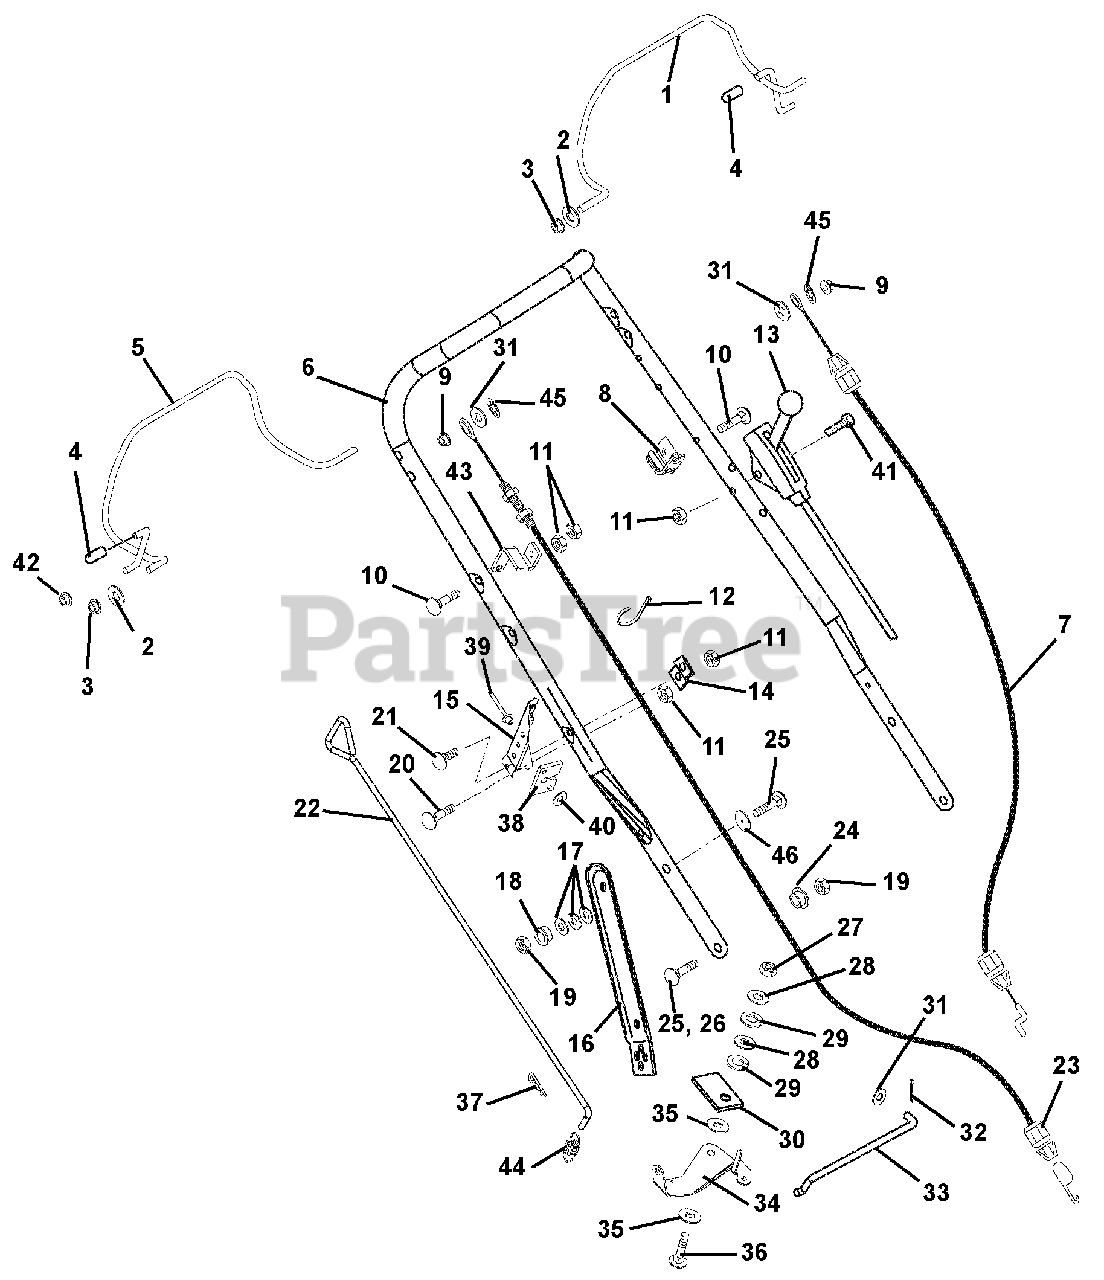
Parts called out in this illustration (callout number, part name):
1	BAIL, WBLM ENGINE
2	@WSHR-FL-STL.344X.688X.065YWZC
3	BSHG-FLG .325X.444X.440X.560
4	CAP, VINYL, .25 ID
5	BAIL, WBLM TRACTION
6	HANDLE BAR, CLASSIC LM21
7	CABLE, ENGINE - ADJUSTABLE
7	CABLE, OPC CLASSIC LM CE DOV
8	BRKT, ENGINE CABLE ANCHOR
9	PUSH NUT, .25
10	BLT-RDHDXLSQNK.25-20X1.25 G5ZC
11	@NUT-LK-CTR .25-20 YWZC
12	CABLE TIE LG 5-1/2
13	CABLE, LOCKOUT CONTROL
14	BRACE, SPEED CONTROL
15	BRKT, SPD CONTROL SLOTTED
16	LINK, HANDLEBAR ADJUSTMENT LH
16	LINK, HANDLEBAR ADJUSTMENT RH
17	WASHER, BELLEVILLE YWZC
18	BSHG-FLG .325X.500X.513X.875
19	@NUT-LK-CTR .31-18 YWZC
20	BLT-RDHDSQNK .25-20X1.38 GR5YZ
21	@BLT-RDHDSQNK .25-20X.50 G5YZ
22	SPEED CONTROL ROD
23	CABLE, WBLM TRACTION
24	BSHG, FLG .325X.499X.26X.88
25	@BLT-RDHDSQNK .31-18X1.00 G5YZ
26	@BLT-RDHDSQNK .31-18X.75 G5YZ
27	@NUT-LK-CTR .38-16 YWZC
28	@WSHR-FL-STL.406X.812X.065 YWZ
29	WSHR-LK .375X.115 HVY YWZC
30	PRESSURE FLANGE
31	@WSHR-FL-STL.281X.62X.065 YWZC
32	@PIN-CTR .06X.50 EXTPRSQCT YWZ
33	SHIFT LINK
34	CRANK, SPEED CONTROL BELL
35	FRICTION WASHER
36	@BLT-RHDSSQNK .38-16X1.25 G5YZ
37	PIN-HAIR INT .08X.18X1.18 YWZC
38	PAD, RUBBER SUPPORT
39	RVT .187X.575 DOME AL BLACK
40	@WSHR-FL-STL.219X.50X.049 YWZC
41	BLT-RDHDXLSQNK .25-20X2.0 G5YZ
42	NUT-PUSH .312 DIA. PAL
43	BRKT, TRACTION CABLE ANCHOR
44	SPRING, EXTENSION
45	RG-RTNG-EXT .250X.010
46	WSHR-FL-STL .505X.880X.072 YWZ
